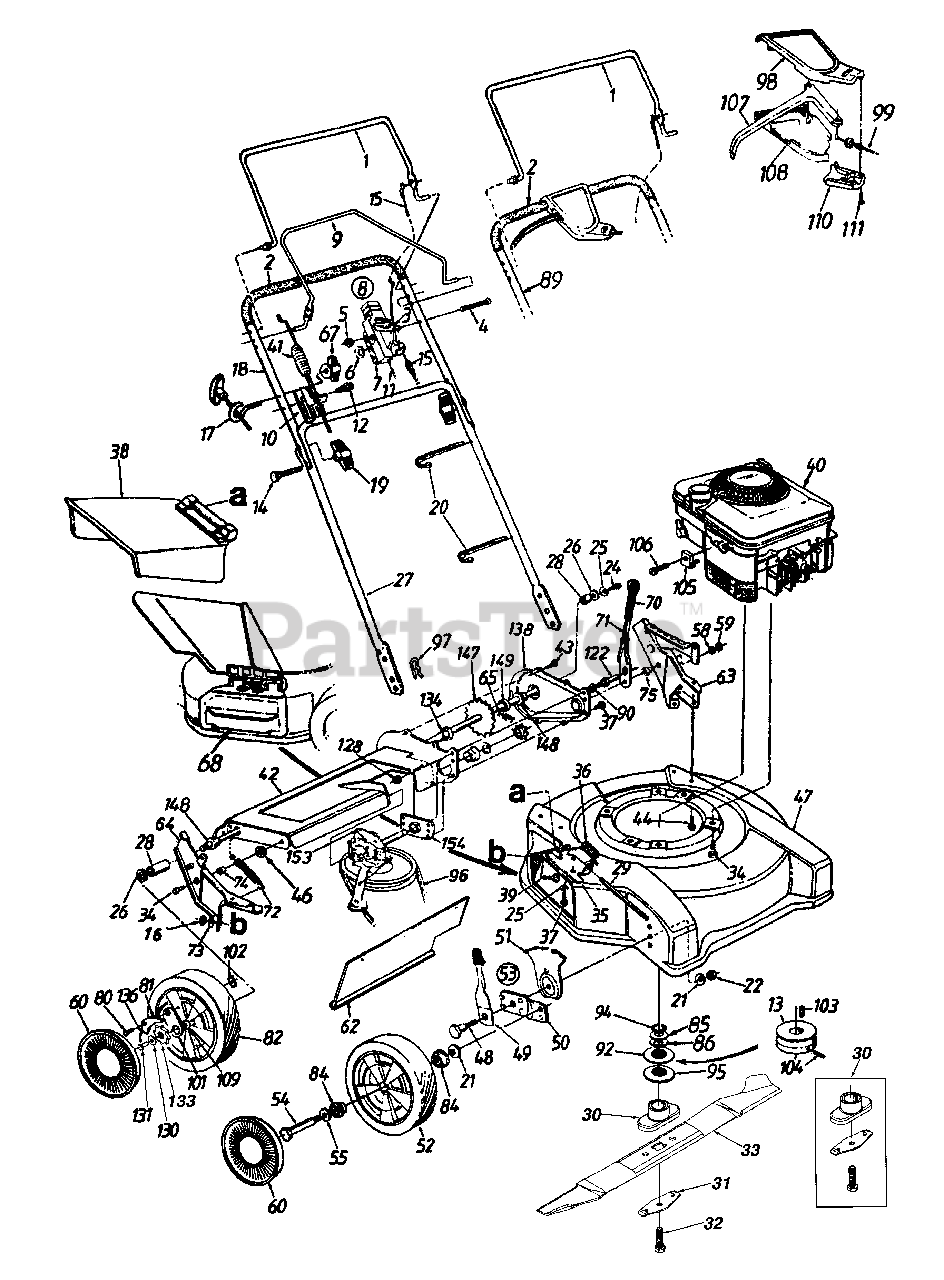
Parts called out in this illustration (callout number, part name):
2	Foam Grip
3	Throttle Lever
4	Oval C-Sunk Scr.
5	Hex L-Nut 1/4-20 Thd.
6	Spr. Wash. .66" I.D.
7	Throttle Body
8	Throttle Box Comp.
11	Throttle Cable 55" Lg.
12	Hex Wash. AB-Tap Scr. 5/16 x .75" Lg.
13	Keyed Pulley
14	Curved Hd. Bolt 5/16-18 x 2"
15	Control Cable 39" Lg.
16	L-Wash. 5/16" I.D.
17	Rope Guide
20	Cable Tie
21	Bell-Wash. .38" I.D. x .88"
22	Hex Nut 3/8-16 Thd.
24	Hex Bolt 1/4-20 x .62" Lg.(Grade 5)
25	Bell-Wash. 1/4" I.D.
26	Fl-Wash. .531" I.D. x .93"
28	Spacer .513" I.D. x .703"
29	Hinge Pin
30	Blade Adapter Kit
31	Blade Bell Support
32	Hex Bolt 3/8-24 x 2.5" Lg.
33	22" Blade
34	Hex L-Wash. Hd. Scr. 3/8-16
35	Adapter Plate
36	Torsion Spring
37	Hex Self-Tap Scr. 1/4-20 x .5"
38	Chute Deflector Ass'y.
39	Carriage Bolt 5/16-18 x .62" Lg.
40	Engine
41	Drive Cable-41.5" Lg. (Dual Bail)
44	Hex Wash. Hd. B-Tap Scr.5/16-18
46	Fl-Wash. .385" I.D. x 1" O.D.
49	Spring Lever Ass'y. w/Knob
51	Height Adj. Plate
52	Wheel Ass'y. Comp.
53	Height Adj. Ass'y. Comp.-R.H.
54	Shld. Bolt .498" Dia. x 1.45"
55	Wave Wash. .51" I.D. x .78"
58	Fl-Wash. .385" I.D. x .87"
59	Hex Patch L-Nut 3/8-24 Thd.
60	Hub Cap
62	Rear Flap
67	Handle Knob 1/4-20 Thd.
68	Mulching Baffle
71	Height Adj. Lever
72	Ext. Spring .5" O.D. x 3.8" Lg.
73	Bell-Wash. 5/16" I.D.
74	Spacer .383" I.D. x .503
75	Shld. Spacer .5" Dia.
80	Shld. Scr. .342" Dia. x .268"
81	Pawl-R.H.
82	Wheel Ass'y. Comp.
84	Bearing
85	Spr. Wash. .89 I.D.
86	Fl-Wash. .885 I.D.
90	L-Wash. 3/8" I.D.
92	Upper Pulley Half
94	Crankshaft Spacer
95	Lower Pulley Half
96	"V"-Belt
97	Hairpin Clip
98	Control Cover-Upper Half
99	S.R Cable (Single Bail)
101	Pawl Plate
102	Weld L-Nut 1/4-20 Thd.
103	Sq. Key 3/16" x 3/4" Lg.
104	Set Scr. #10-32 x .25" Lg.
105	Cable Clamp
106	Hex Wash. Hd. Scr. #10-32 x .62" Lg.
107	Control Lever
108	Control Cover-Lower Half
109	Sleeve Brg. 1/2" I.D.
110	Mounting Cap
111	Fl-"C"-Sunk Hd. Tap Scr. #10 x .75" Lg.
122	Shld. Pin 3/8-24 x 1.43" Lg.
128	Hex Jam Nut 3/8-24 Thd.
130	Bell Washer .265 I D x .75
131	Cap Screw HH 1/4-20 x .620
133	Ratchet Wheel 1.62" O.D.
134	Hex Flange Bearing
136	Spring-Nylon
148	Hex Flange Bearing
149	Fl-Wash. .531" I.D. x .93"
153	Transmission Comp
